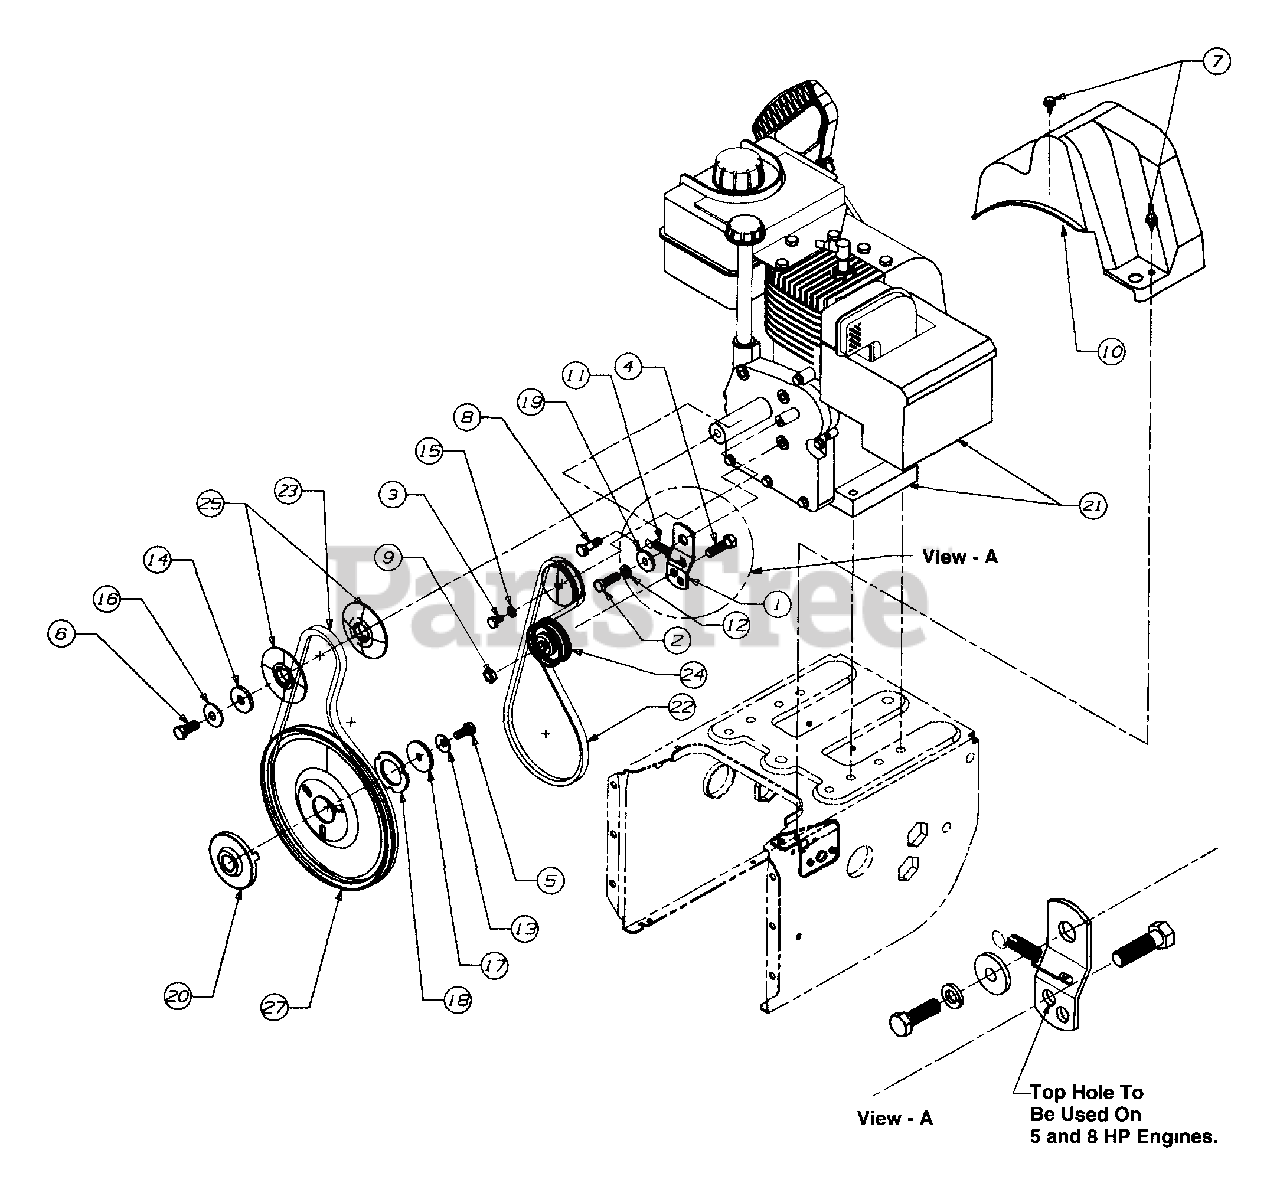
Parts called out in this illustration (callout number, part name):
3	Hex Screw
4	Screw, Hex
5	Screw, Hex
6	Screw, Hex
7	Screw, Hex
8	Screw, Hex
9	Hex Jam Nut
10	Belt Cover
11	Spring
12	Lock Washer
13	Washer, Bell
14	Flat Washer
15	Washer, Flat
16	Washer, Bell
17	Washer, Flat
18	Washer
19	Shoulder Spacer
20	Pulley, Adapter
21	Eng., HSSK Tec. 5.0 HP, Horz.
22	V-Belt
23	V-Belt
24	Idler, Flat
25	Pulley, Half
27	Pulley, Auger
